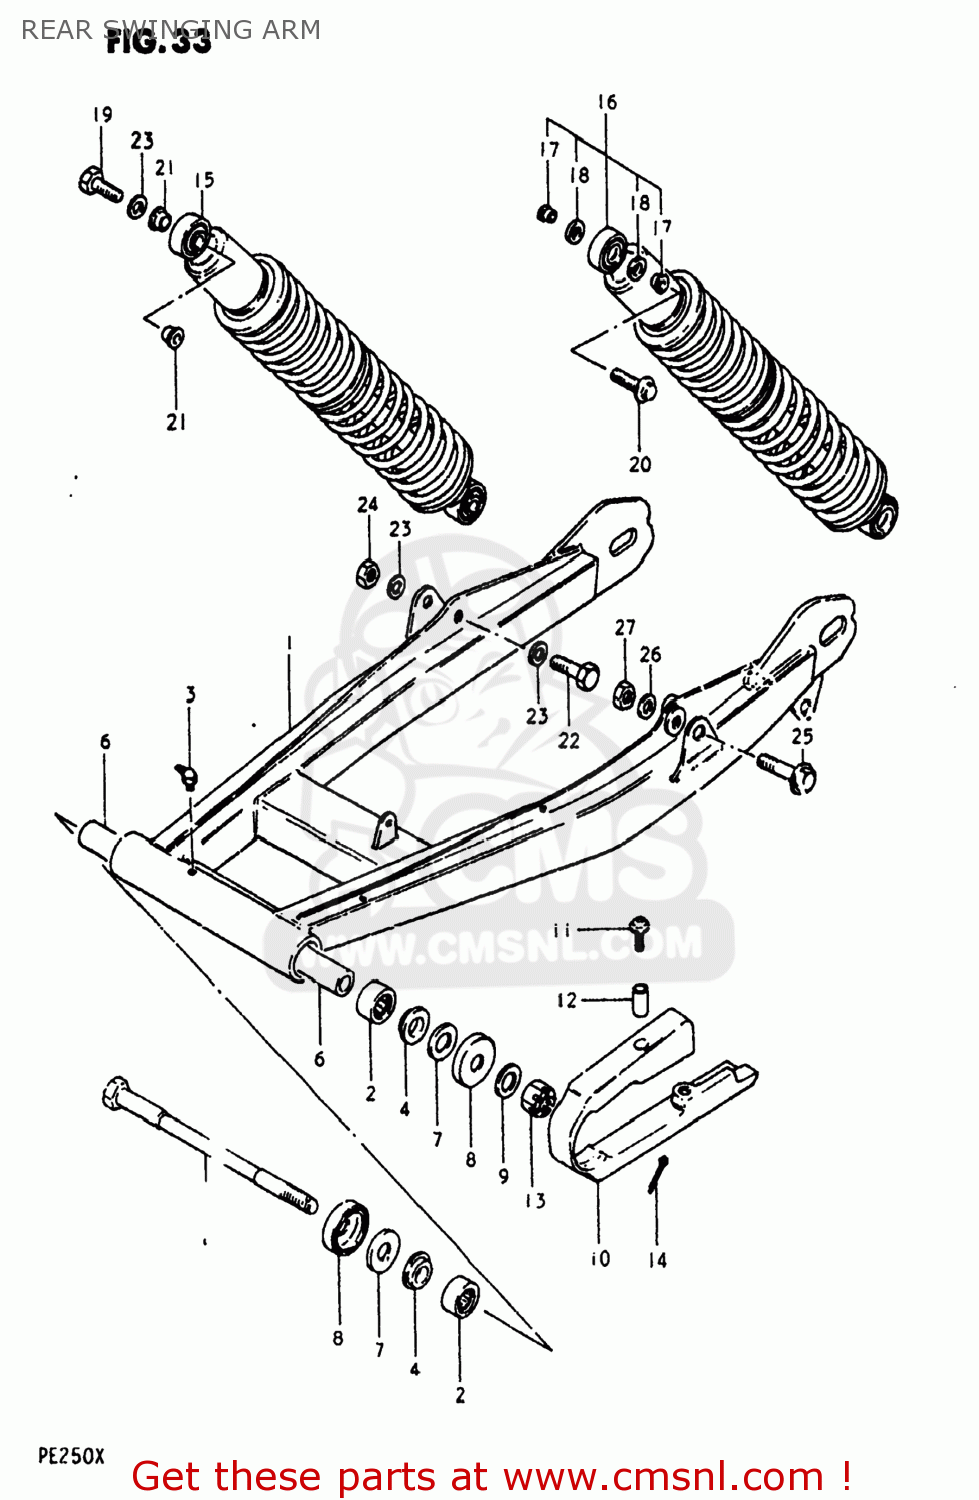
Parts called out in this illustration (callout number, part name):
1	SWING ARM ASSEMBLY,REAR
2	BEARING
3	NIPPLE,GREASE
4	BUSHING,REAR SWING ARM PIVOT
5	SHAFT,REAR SWING ARM
6	SPACER,REAR SWING ARM
7	WASHER
8	COVER,RR SWGARM DUST SEAL
9	WASHER
10	BUFFER,CHAIN TOUCH DEFLECTOR
11	SCREW,CHAIN TOUCH DEFEND
12	SPACER (5.5X8X4)
13	NUT 14MM
14	COTTER PIN
15	ABSORBER ASSEMBLY,REAR SHOCK
16	ABSORBER ASSEMBLY,REAR SHOCK
17	SPACER,REAR SHOCK ABSORBER
18	DUST SEAL,REAR SHOCK
19	BOLT
20	BOLT 10X40
21	SPACER,RR SHK ABS INNER
22	BOLT(8X46)
23	WASHER
24	NUT
25	BOLT(10X52)
26	WASHER
27	NUT
